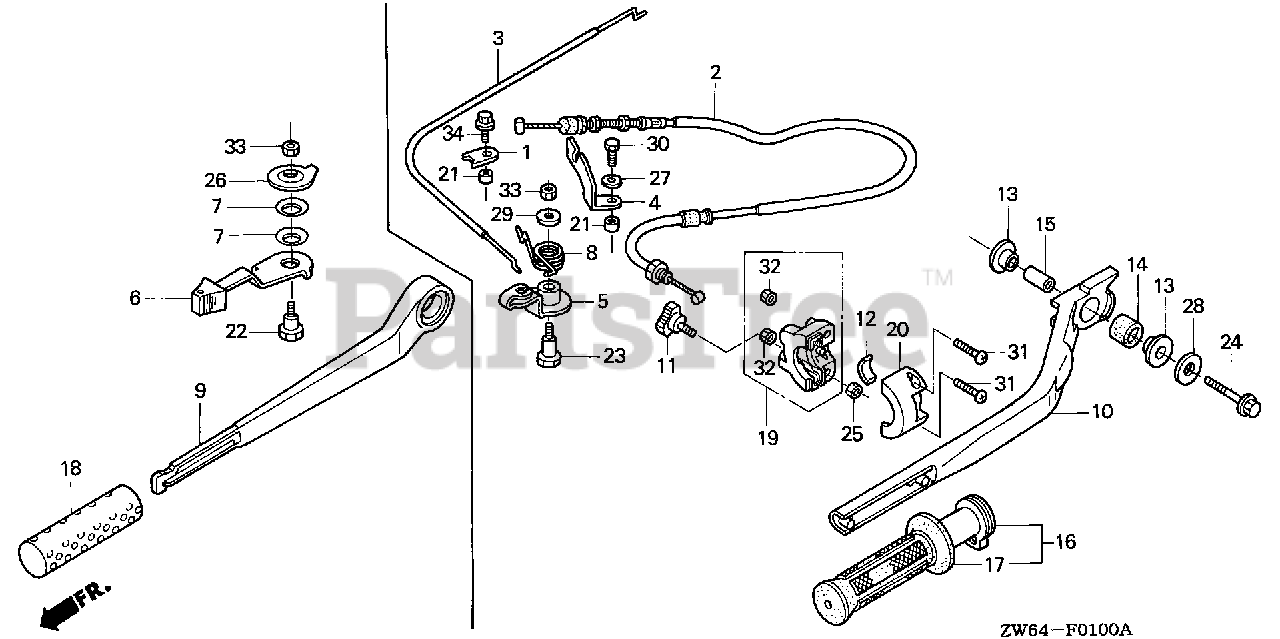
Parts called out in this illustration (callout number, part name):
1	HOLDER, CABLE
2	CABLE A, THROTTLE
3	CABLE B, THROTTLE
3	CABLE, THROTTLE (B)
4	HOLDER, CABLE
5	ARM, THROTTLE
8	SPRING, THROTTLE ARM
11	BOLT, FRICTION
12	BLOCK, THROTTLE FRICTION
16	GRIP, THROTTLE
17	GRIP, R. HANDLE
19	HOUSING, THROTTLE (LOWER)
20	HOUSING, THROTTLE (UPPER)
21	COLLAR, SEAT CATCH
23	BOLT, HEX. (6X24)
25	NUT, U (6MM)
25	NUT, HEX. (6MM)
29	WASHER, PLAIN (6MM)
30	BOLT, HEX. (6X14)
31	SCREW, PAN (5X20)
32	NUT, HEX. (5MM)
33	NUT, HEX. (6MM)
34	BOLT, FLANGE (6X12)
